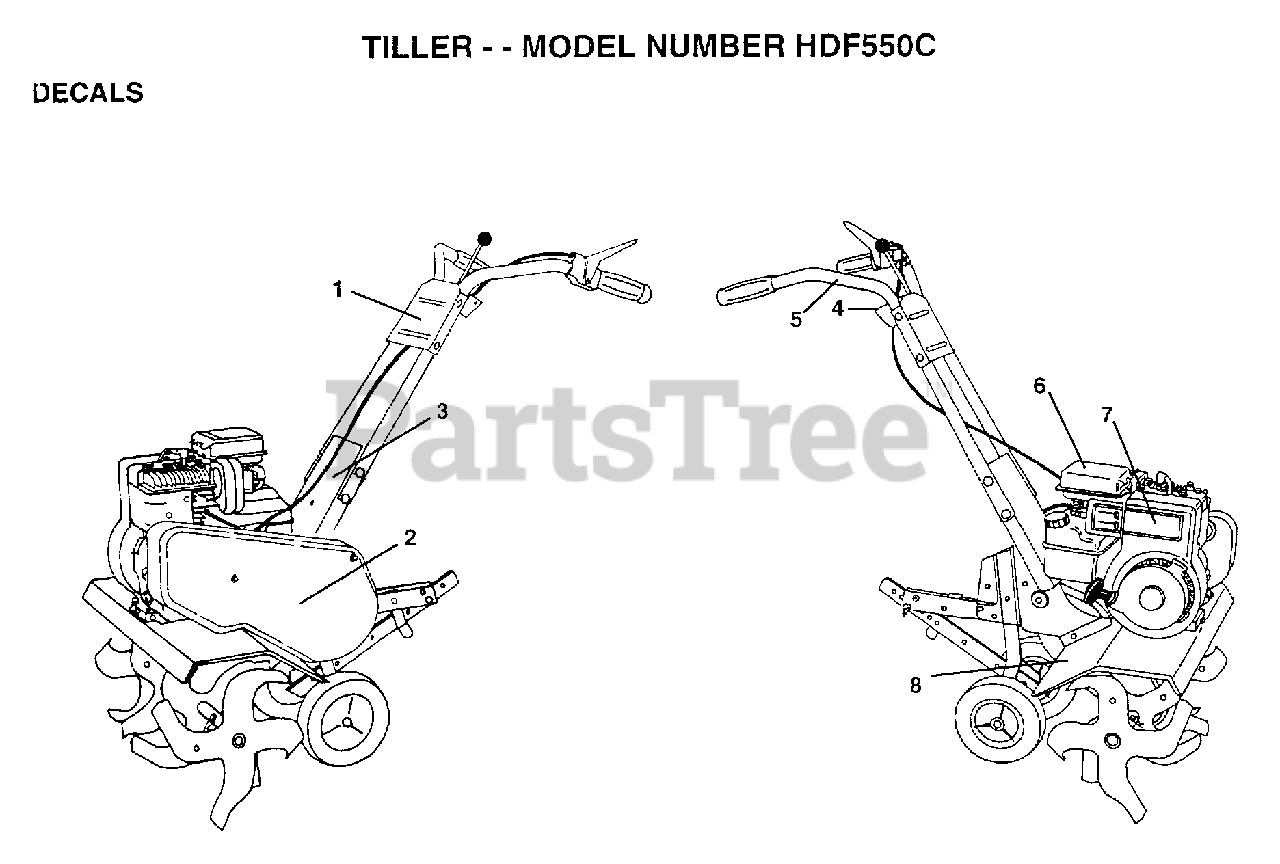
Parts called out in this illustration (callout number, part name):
1	DECAL.PNL.CNTRL.U
2	DECAL.GRD.BLT.WEE
3	DECAL.PNL.CNTRL.L
4	DECAL.PNL.CTRL.ES
5	DECAL.HAND.PLACE
6	DECAL.CAUTION.E/S
7	DECAL, BRIGGS & STRATTON
8	DECAL.WARN.ROT.TI
